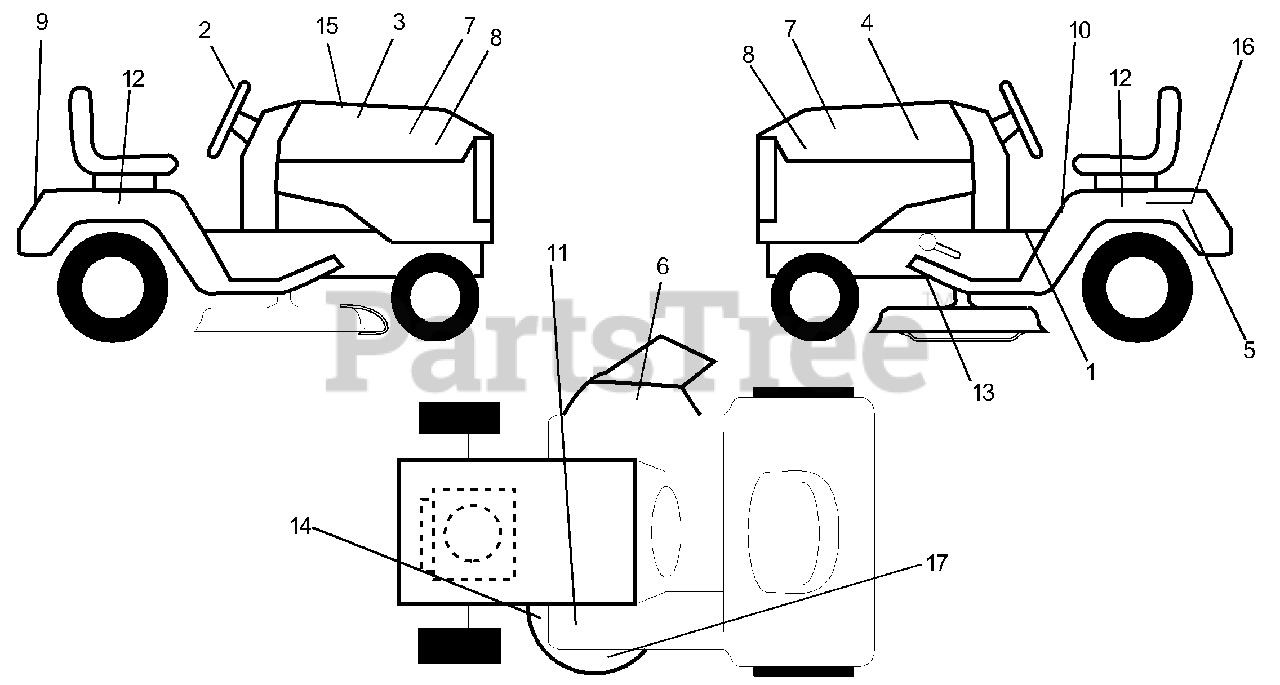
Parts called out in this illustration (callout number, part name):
1	Decal Instruction Operat English
2	Decal Ins Strg Wh
3	Decal Hood Rh
4	Decal Hood Lh
5	Decal Battery
7	Decal Panel Side
8	Decal Panel Side
9	Decal Fender Logo
10	Decal Danger English
11	Decal Clutch/brake English
12	Decal Fender Auto Rad
13	Decal V-Belt Drive Sch
14	Decal V-belt Schematic 42"
15	Decal Replacement Parts
16	Decal Battery Danger/Poison
17	Decal Deck Enviro
